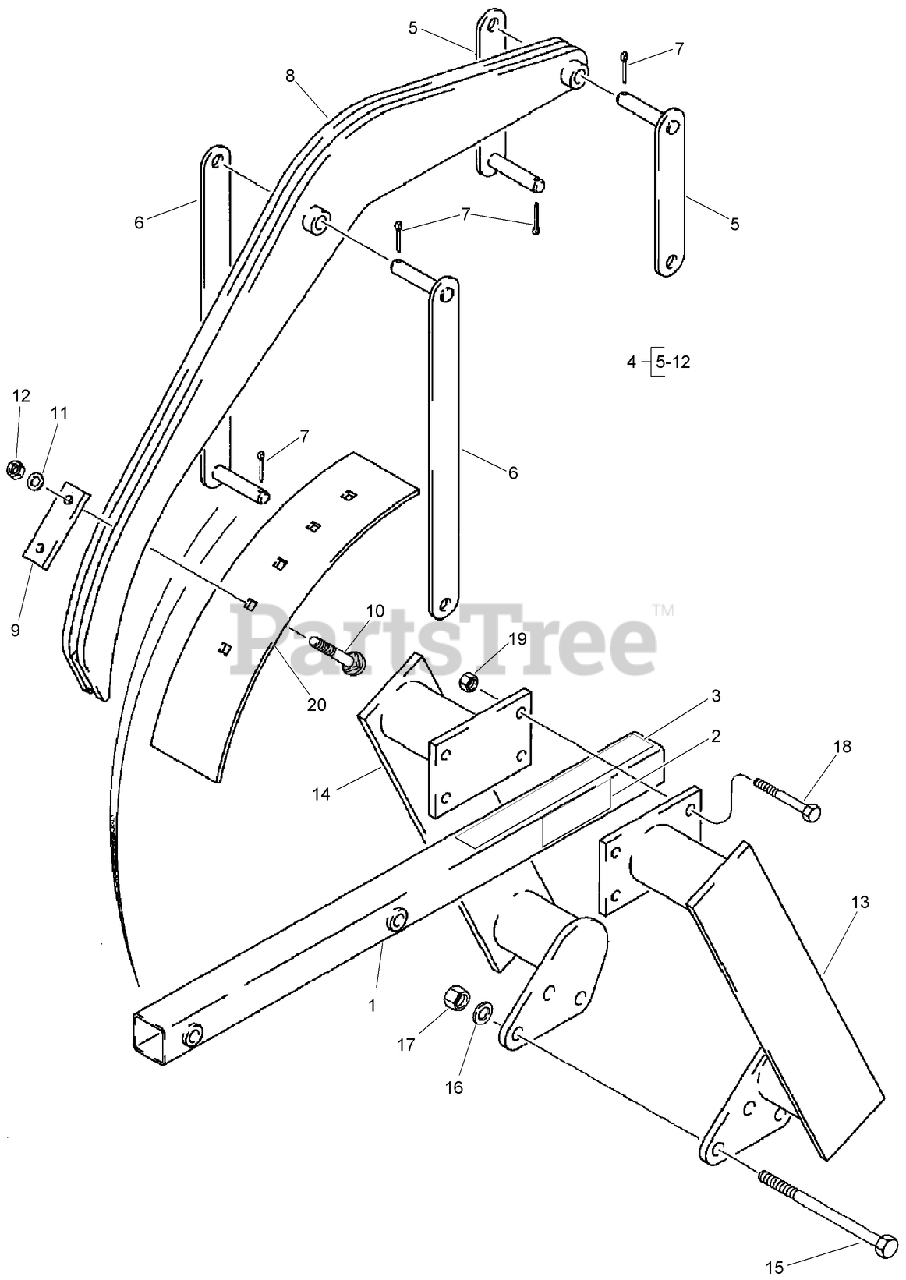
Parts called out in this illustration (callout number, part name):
1	BOOM-crumber, 4 foot, heavy duty planetary trencher
1	BOOM-crumber, 5 foot, heavy duty planetary trencher
1	BOOM-crumber, 6 foot, heavy duty planetary trencher
1	GUARD-digging chain, 4 foot, units without crumber, if used
1	GUARD-digging chain, 5 foot, units without crumber, if used
1	GUARD-digging chain, 6 foot, units without curmber, if used
2	DECAL-Danger, Entanglement Hazard
3	DECAL-Danger
4	I / BASIC CRUMBER ASM
5	LINK-boom to crumber, short
6	LINK-boom to crumber, long
7	PIN-cotter, 3/16 x 1-1/4 inch
8	BRACKET-crumber blade
9	PLATE-spacer, bracket to blade
10	BOLT-CARR
12	NUT-HEX
13	MOUNT-Crumber, RH
13	MOUNT-Crumber LH
14	MOUNT-Crumber, LH
14	MOUNT-Crumber RH
16	WASHER-Flat
17	NUT-Prev Trq 3/4 GRC CAD Direct
18	SCREW-HH
19	NUT-HEX
20	BLADE-crumber, 6 inch wide, if used
20	BLADE-crumber, 8 inch wide, if used
20	BLADE-crumber, 10 inch wide, if used
20	BLADE-crumber, 11 inch wide, if used
20	BLADE-crumber, 13 inch wide, if used
20	BLADE-crumber, 16 inch wide, if used
